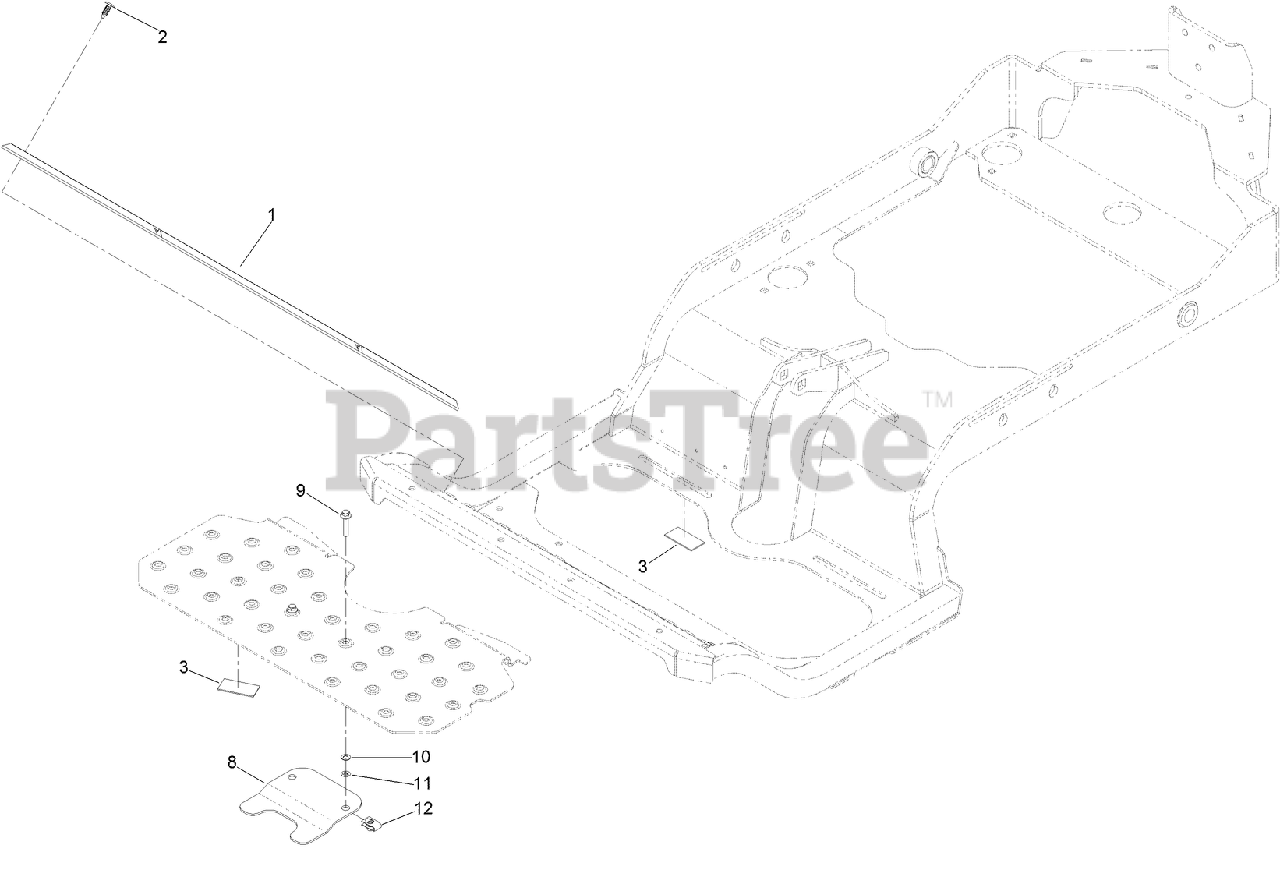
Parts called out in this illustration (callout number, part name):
1	MAT-FLOOR
2	PLUG-PLASTIC
3	PAD-RUBBER
8	ADAPTER-CAPTIVE
9	SCREW-HHF
10	WASHER-FLAT
11	NUT-RETAINER
